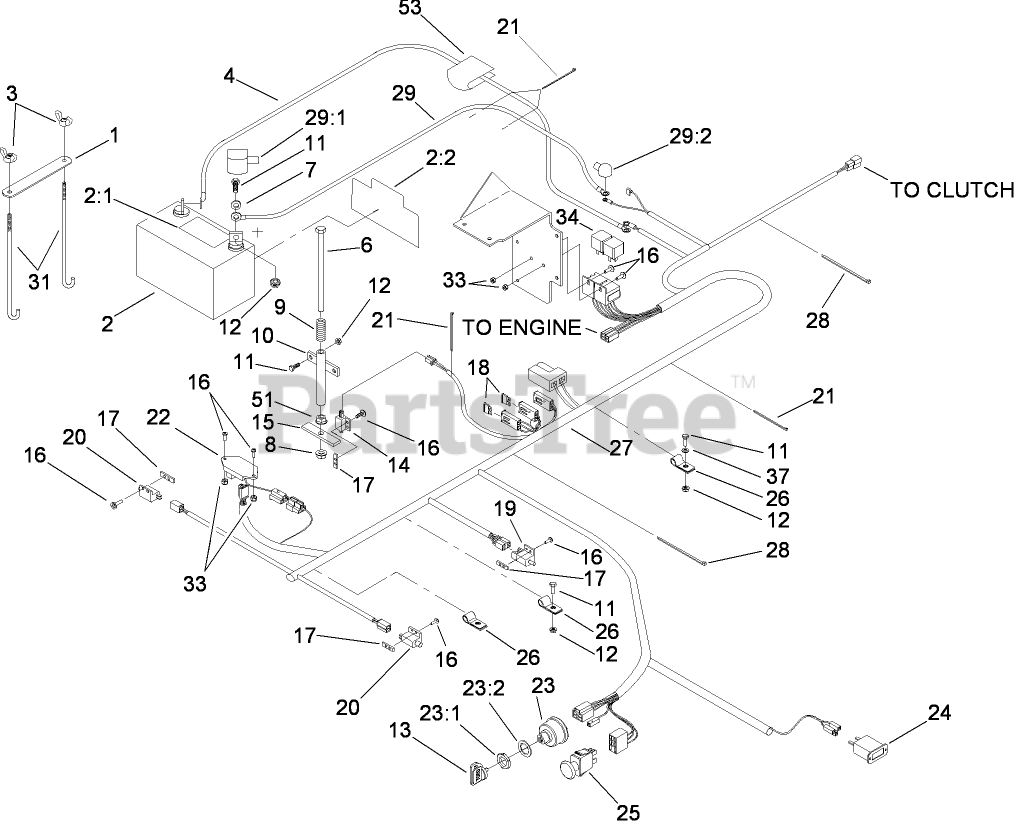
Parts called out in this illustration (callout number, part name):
1	STRAP-HOLDDOWN, BATTERY
2	BATTERY
2:1	Decal-Battery
2:2	Decal-Battery
3	WINGNUT
4	WIRE-GROUND
6	SCREW-HH
7	WASHER-FLAT
8	NUT-LOCK, NI
9	SPRING-SWITCH, SEAT
10	MOUNT-SPRING, SEAT
11	SCREW-HH
12	NUT-HF
13	KEY-IGNITION
14	SWITCH-CLOSED, NORMALLY
15	PLATE-SWITCH, SEAT
16	SCREW-PPH
17	PLATE-TAPPED
18	FUSE-BLADE TYPE, 20 AMP
19	SWITCH
20	SWITCH-OPEN, NORMALLY
21	TIE-CABLE
22	MODULE-DELAY, SEAT
23	SWITCH ASM
23:1	NUT-HH
23:2	WASHER-TOOTH, INTERNAL
24	METER-HOUR
25	SWITCH-PTO
26	CLIP-LOOM
27	Harness-Wire
28	TIE-PLASTIC
29	POSITIVE BATTERY CABLE ASM
29:1	INSULATOR-BATTERY
29:2	INSULATOR-SOLENOID
31	BOLT-HOLDDOWN
33	NUT-LOCK, NI
37	WASHER-FLAT
51	NUT-HEX
53	DECAL-INSTRUCTIONS, CHARGING
